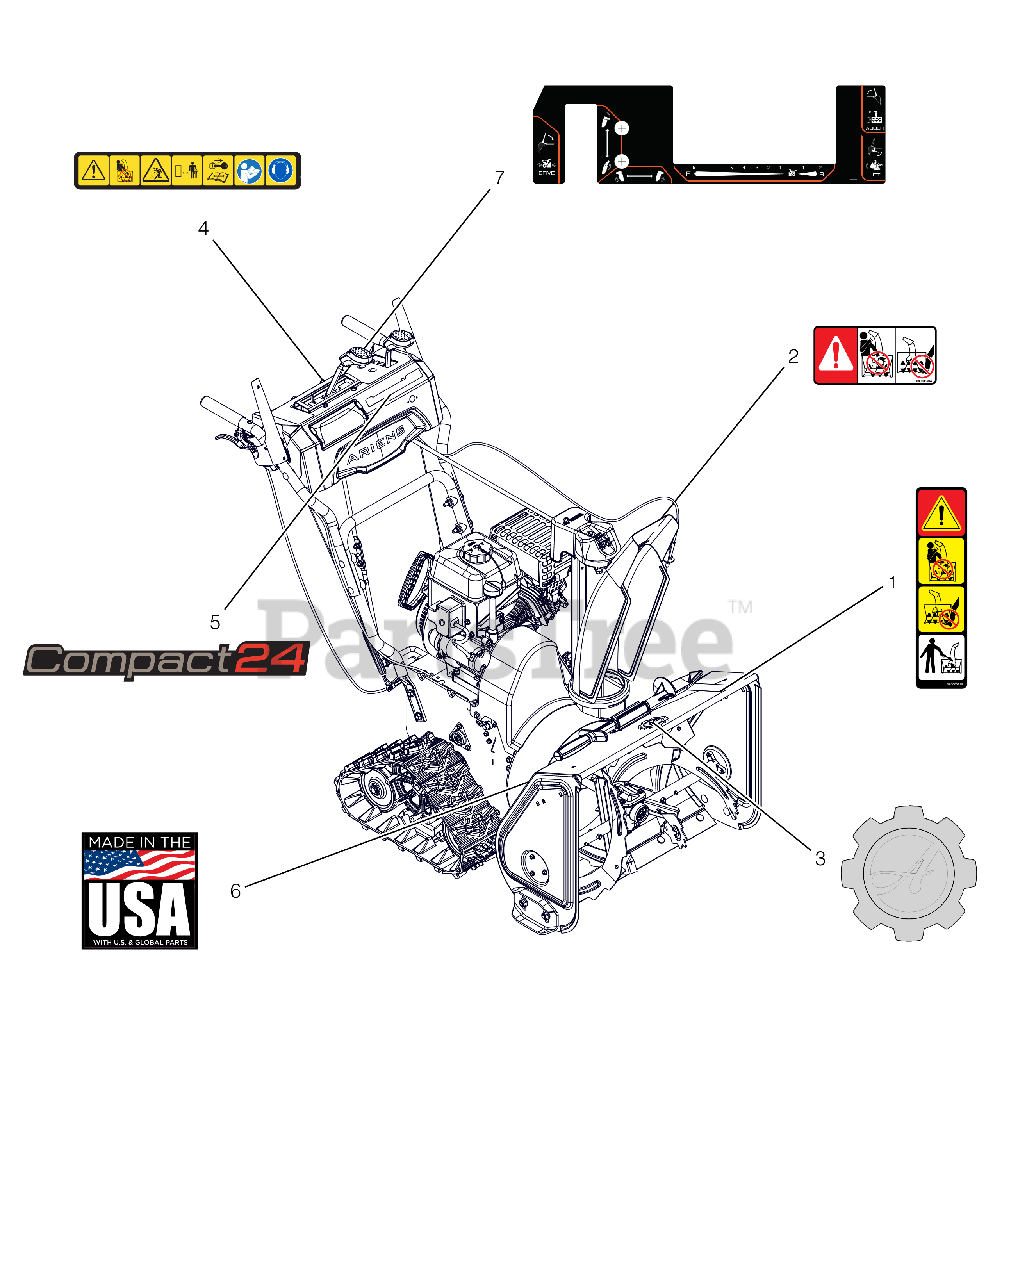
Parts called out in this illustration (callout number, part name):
1	DECAL, DANGER - ROTATING PARTS
2	DECAL, DANGER
3	DECAL, ARIENS-GEAR BADGE -THK
4	DECAL,DASH - SAFETY
5	DECAL, DASH - COMPACT 24
6	DECAL, MADE IN USA
7	DECAL,CONTROL-COMP TRACK
